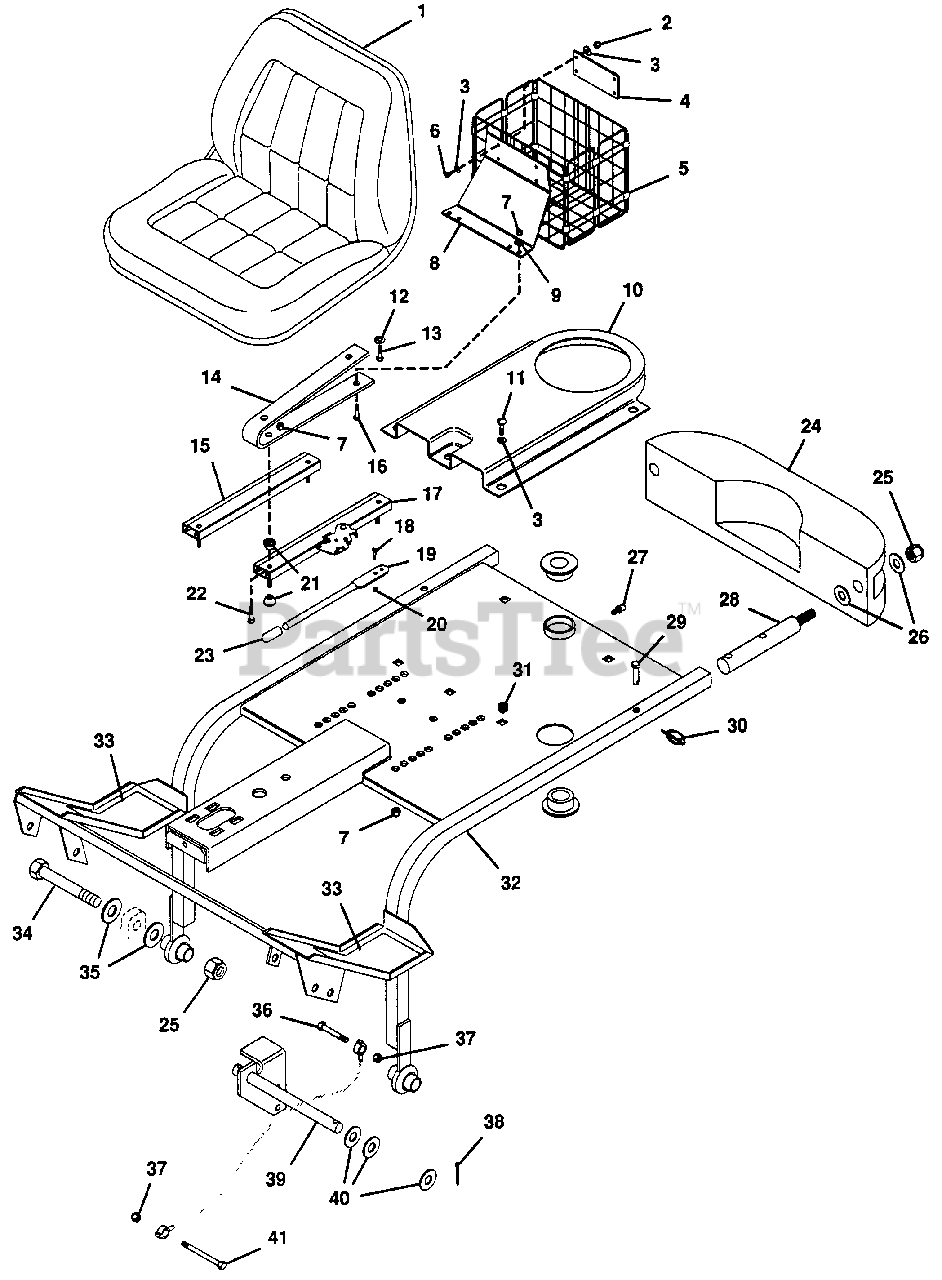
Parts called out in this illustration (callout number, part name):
1	Seat, Pro Master
2	Nut, Lock 1/4-20
3	Washer, Flat .281x.625x.065
4	Strap, Basket
5	Basket
6	Bolt, Hex 1/4-20x1.00
7	Nut, Lock 5/16-18
8	Bracket, Basket
9	Washer, Flat .344x.688x.065
10	Cover, Chain
11	Screw, Tapping 1/4-20x.625 PHD
12	Washer, Lock 5/16
13	Bolt, Hex 5/16-18x.75
14	Spring, Seat
15	Adjuster, Seat
16	Bolt, Hex 5/16-18x2.00
17	Adjuster, Seat w/Latch
18	Screw, Machine 10-24x.625 PHD
19	Handle, Seat Slide
20	Nut, Lock 10-24
21	Spacer
22	Bolt, Hex 5/16-18x1.25
23	Tip, Lever
24	Weight, Pro Master-60
25	Nut, Lock 3/4-10
26	Washer, Flat .813x2.0x.148
27	Fitting, Lube 1/4-28
28	Shaft, Weight
29	Pin, Clevis 3/8x2.62
30	Pin, Klik
31	Grommet, Plastic
32	Weldment, Frame
33	Cover, Footboard
34	Bolt, Hex 3/4-10x3.75
35	Washer, Flat .812x1.469x.130
36	Bolt, Hex 5/16-24x2.25
37	Nut, Lock 5/16-24
38	Pin, Cotter .125x1.25
39	Weldment, Lift Bracket
40	Washer, Flat .656x1.250x.100
41	Bolt, Hex 5/16-24x3.50
